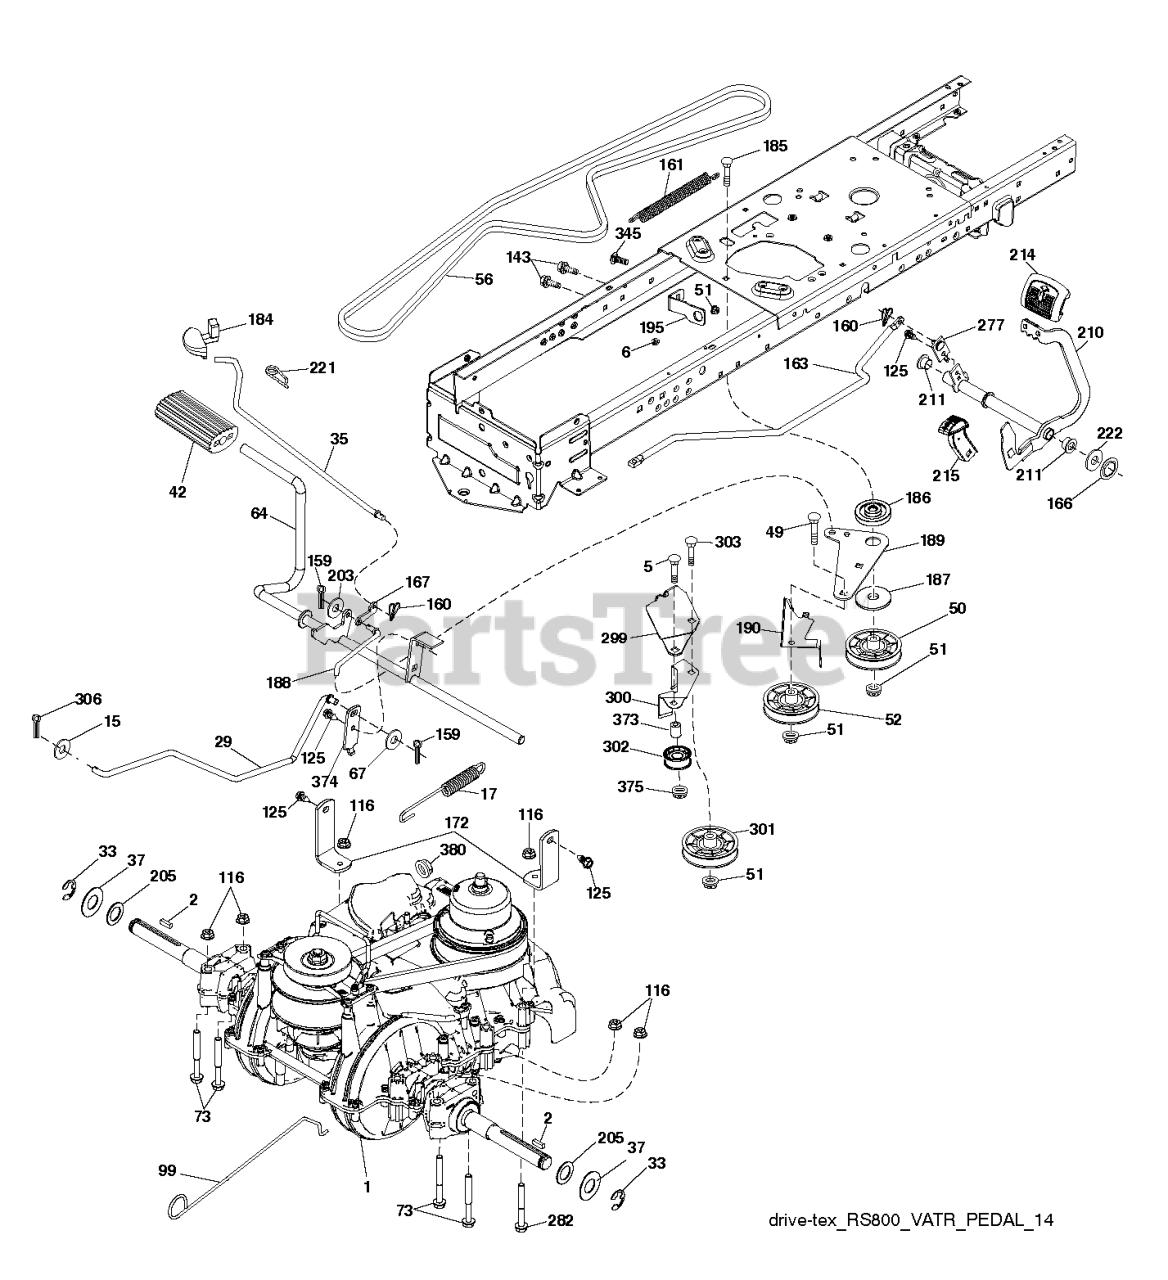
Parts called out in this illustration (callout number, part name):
2	SQUARE KEY
6	BUSHING.SNAP.NYL.BLK.
15	WASHER
17	SPRING.BRAKE.VARIATOR
29	BRAKE.VARIATOR.SD3
35	ROD .BRAKE. PARKING. GT. HUSQ.
37	WASHER.HARDENED
42	PEDAL COVER T
49	BOLT
50	IDLER.FLAT.910.OFFSET
51	NUT LOCK FLG 3/8-16 UNC
52	IDLER.V-GROOVE.910.OFFSET
56	BELT.DRIVE.MOWER.TEX.42"
64	SUBASM.SHAFT.PEDAL.BRAKE
67	WASHER.NYLON;13/32X13/16X.109
73	BOLT HEX 5/16-18 GR 5
99	ROD.BYPASS.VARIATOR.GEN2
116	NUT LOCK HEX FLANGE 5/16-18
125	SCREW
143	Screw 5/16-18 x 1/2 Hex, Self Tapping 5/16-18 x 1/2
159	COTTER PIN
160	RETAINER CLIP
161	SPRING, RETURN LT
163	ROD.CONTROL.PEDAL.VARIATOR
166	NUT.PUSH.625
167	LATCH.BRAKE.SPRING
172	STRAP.TORQUE.VARIATOR
184	HANDLE.PARKING.BRAKE.H (BLK)
186	SPACER.RETAINER
187	WASHER 12/32X2X10GA
188	LINK.CLUTCH.GROUND DRIVE.LONG
189	BELLCRANK.GROUND.DRIVE.TEX.
190	KEEPER.BELLCRANK.DRIVE
195	BRACKET.BRAKE.BRAKE.VAR.SD
203	WASHER
210	WELDMENT.PEDAL.VARIATOR
211	BUSHING.SHAFT.BRAKE.HAND
214	PEDAL.FORWARD.PAD.TEX
215	PEDAL.REVERSE.VARIATOR.MS428
221	RETAINER.SPRING.CLIP.H
222	WASHER 21/32 X 1-1/4 X 10 GA.
277	SUBASM.LINK.ROCKER.PEDAL
282	BOLT HEX FLGHD 5/16-18X3 GR. 5
299	BRACKET.MOUNT.IDLERS
300	KEEPER.IDLERS.REAR.VARIATOR
301	PULLEY.IDLER.V-GROOVE
303	BOLT CARRIAGE
306	PIN COTTER
345	BOLT
373	SPACER.IDLER
374	ARM.CONTROL.BRAKE
375	LOCKNUT
380	NUT.FLG.NYLOCK.1/4-20.GR.G.ZY
